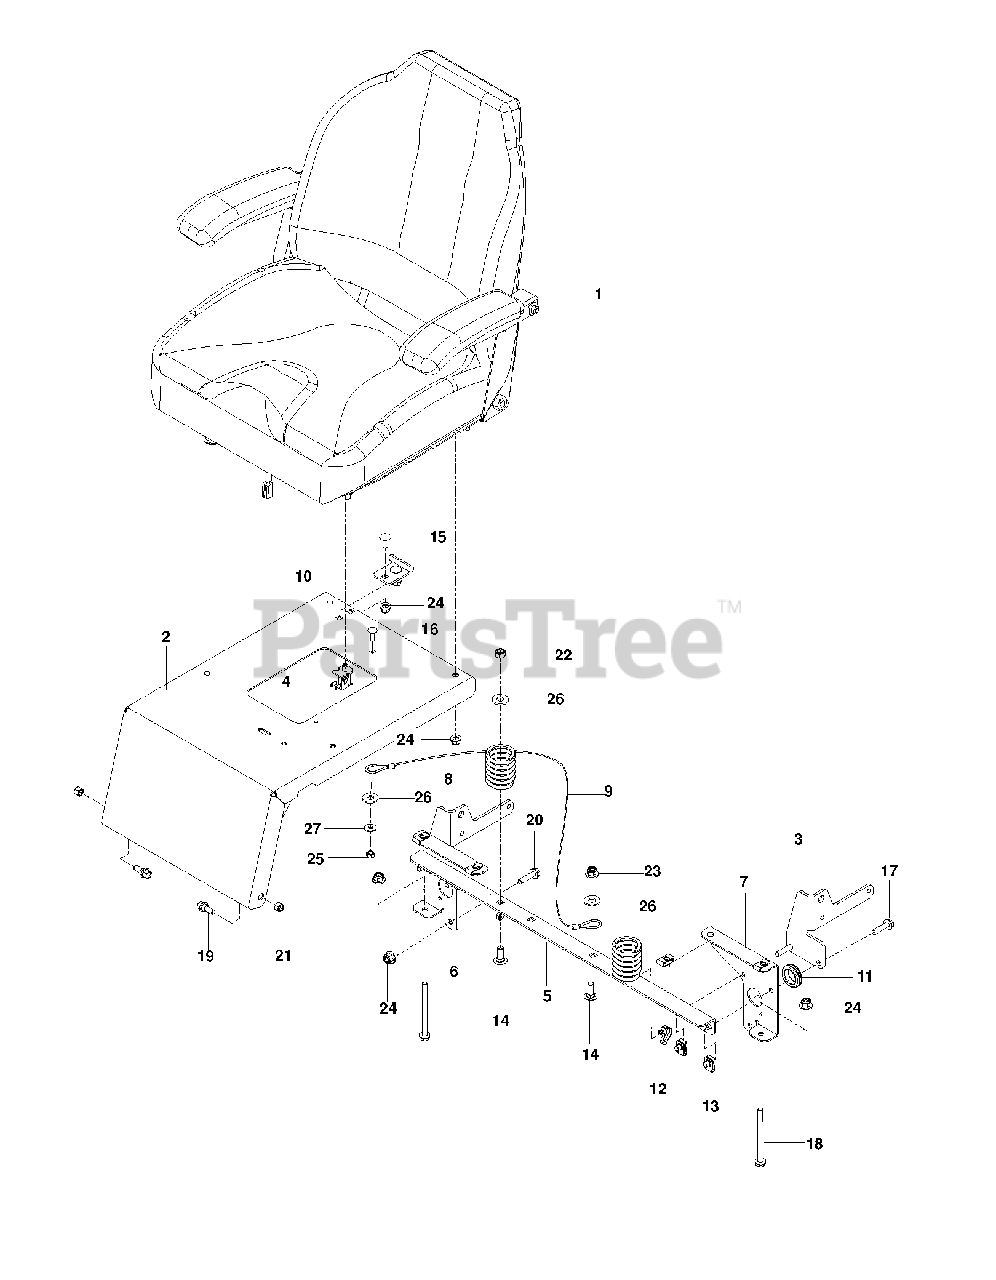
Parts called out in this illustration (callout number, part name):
2	SEAT MOUNT, W/DECALS
3	MOUNT, SEAT BELT, BLACK
4	SEAT SWITCH
5	SUPPORT, SEAT
6	SUPPORT, RT, BLK
7	SUPPORT, LT, BLK
8	SPRING, SEAT
9	SEAT LANYARD
10	STOP, SEAT - BLACK
12	TIE WRAP, 8-3/8", W/CLIP
13	U-CLIP 5/16-18 NUT RETAINER
14	RHSNB 3/8C X 1
15	RHSNB 5/16-18 X 3/4
16	RHSNB 1/4C X 3/4
17	HHFS 5/16-18 X 1.25 TPBLT GD 5
18	HHFS 5/16-18 X 3 3/4
19	SB 5/16-18 HEX HD GD5, BLK ZN
21	NUT 5/16 NYLOC
22	NUT 3/8-16 NYLOC
23	NUT 3/8-16 HEX FLG NYLOC ZD
24	5/16-18 NYLOC FLANGE NUT
25	NUT 1/4-20 NYLOC
26	WASHER 3/8 FLAT
27	WASHER 1/4 FLAT
